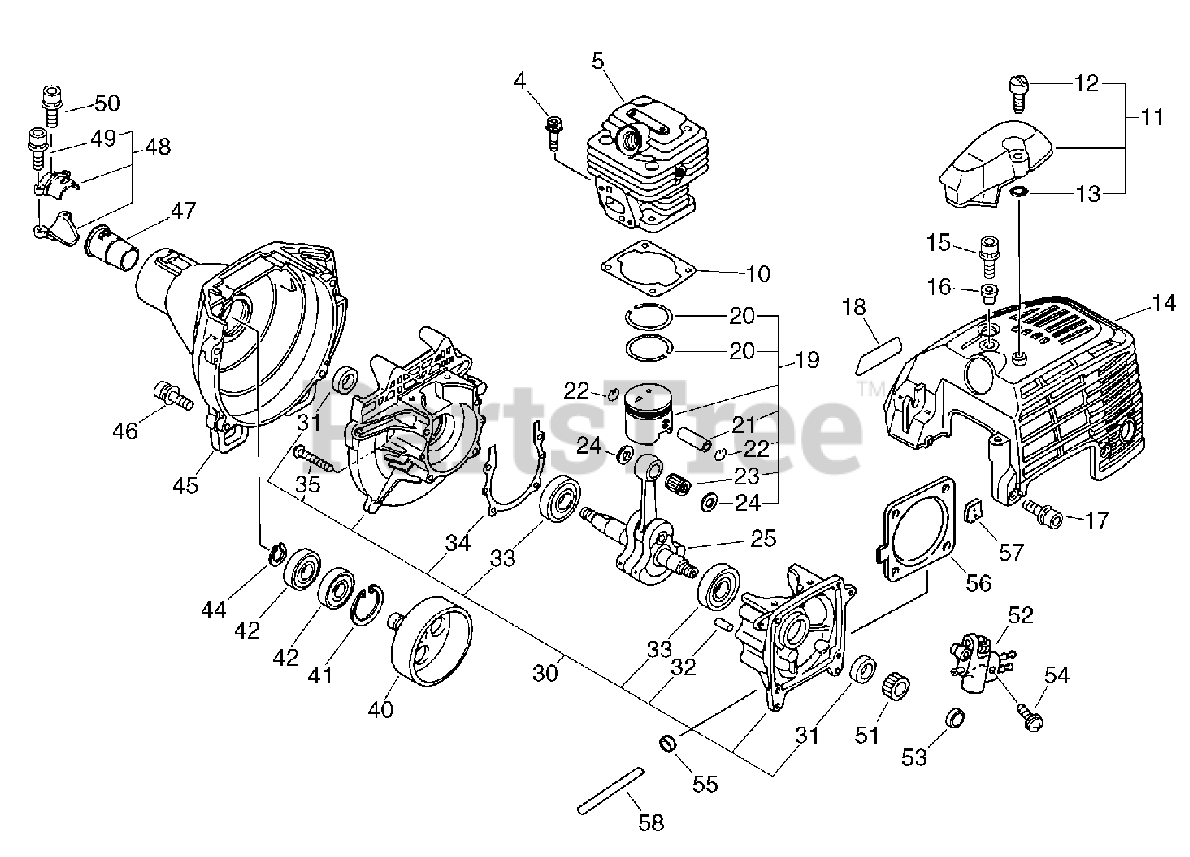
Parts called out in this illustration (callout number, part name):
4	SCREW - 5X20
5	CYLINDER
10	GASKET, CYLINDER
11	GUARD KIT
12	KNOB, FASTENER
13	O-RING - 4
14	COVER, ENGINE
15	SCREW - 5X20
17	SCREW - 5X12
18	LABEL - MODEL
19	PISTON KIT
20	RING, PISTON
21	PIN, PISTON
22	RING, RETAINING
23	BEARING, NEEDLE
24	SPACER, PISTON
25	CRANKSHAFT ASSY
30	CRANKCASE KIT
31	SEAL, OIL
32	PIN - LOCATING
33	BEARING, BALL - 6201
34	GASKET, CRANKCASE
35	SCREW - 5X30
40	DRUM, CLUTCH
41	RING, RETAINING - 28
42	BEARING, BALL - 6001
44	RING, RETAINING - 12
45	COVER, FAN
46	SCREW - 5X20
47	CUSHION
48	HOLDER KIT
49	SCREW - 5X25
50	SCREW - 5X12
51	GEAR - WORM
52	AUTO-OILER ASSY
53	COLLAR - 8
54	SCREW - 4X16
58	PIPE - 2X4X115
